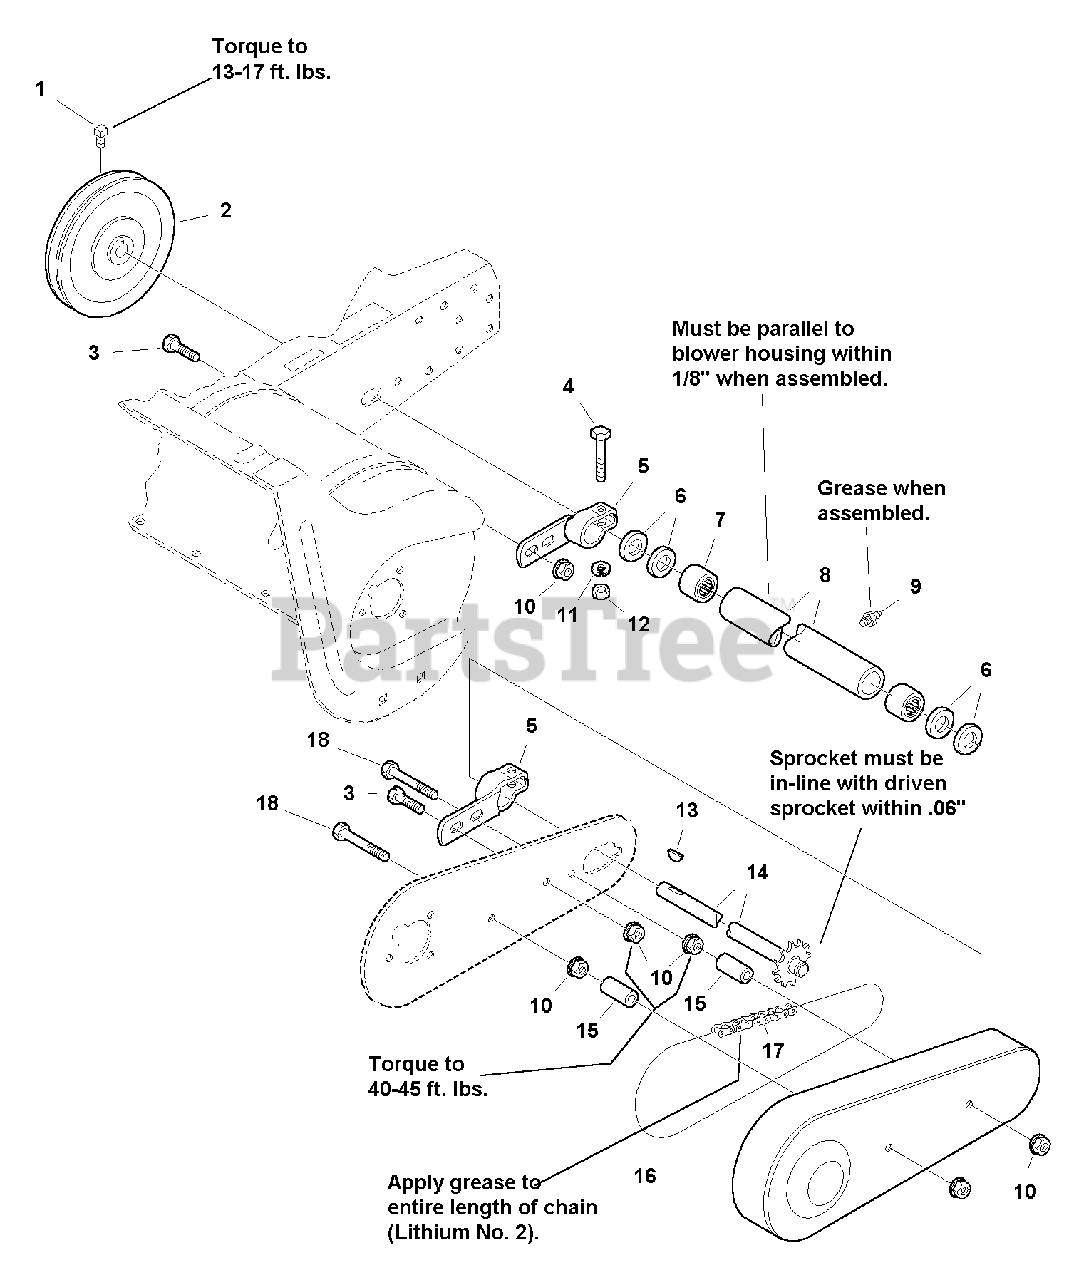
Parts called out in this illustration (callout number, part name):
1	SETSCREW, 5/16-18 X 1/2, G8
3	CAPSCREW, Hex Head Whizlock, 3/8-16 x 1
4	SCREW, Hex Head Cap, 5/16-18 x 1 3/4
7	BEARING, Needle
8	HOUSING ASSEMBLY, w/Bearings (Includes Ref. No. 7)
9	FITTING, Grease
10	LOCKNUT, Flange, 5/16-18
11	LOCKWASHER, 5/16
12	NUT, Hex, 5/16-18
13	KEY
14	SHAFT & SPROCKET ASSEMBLY, 12 Tooth
16	GUARD, Chain
17	CHAIN (Auger Drive), #40, 32" Long, 64 Pitch
18	CAPSCREW, Hex Head Whizlock, 3/8-16 x 2-3/4
